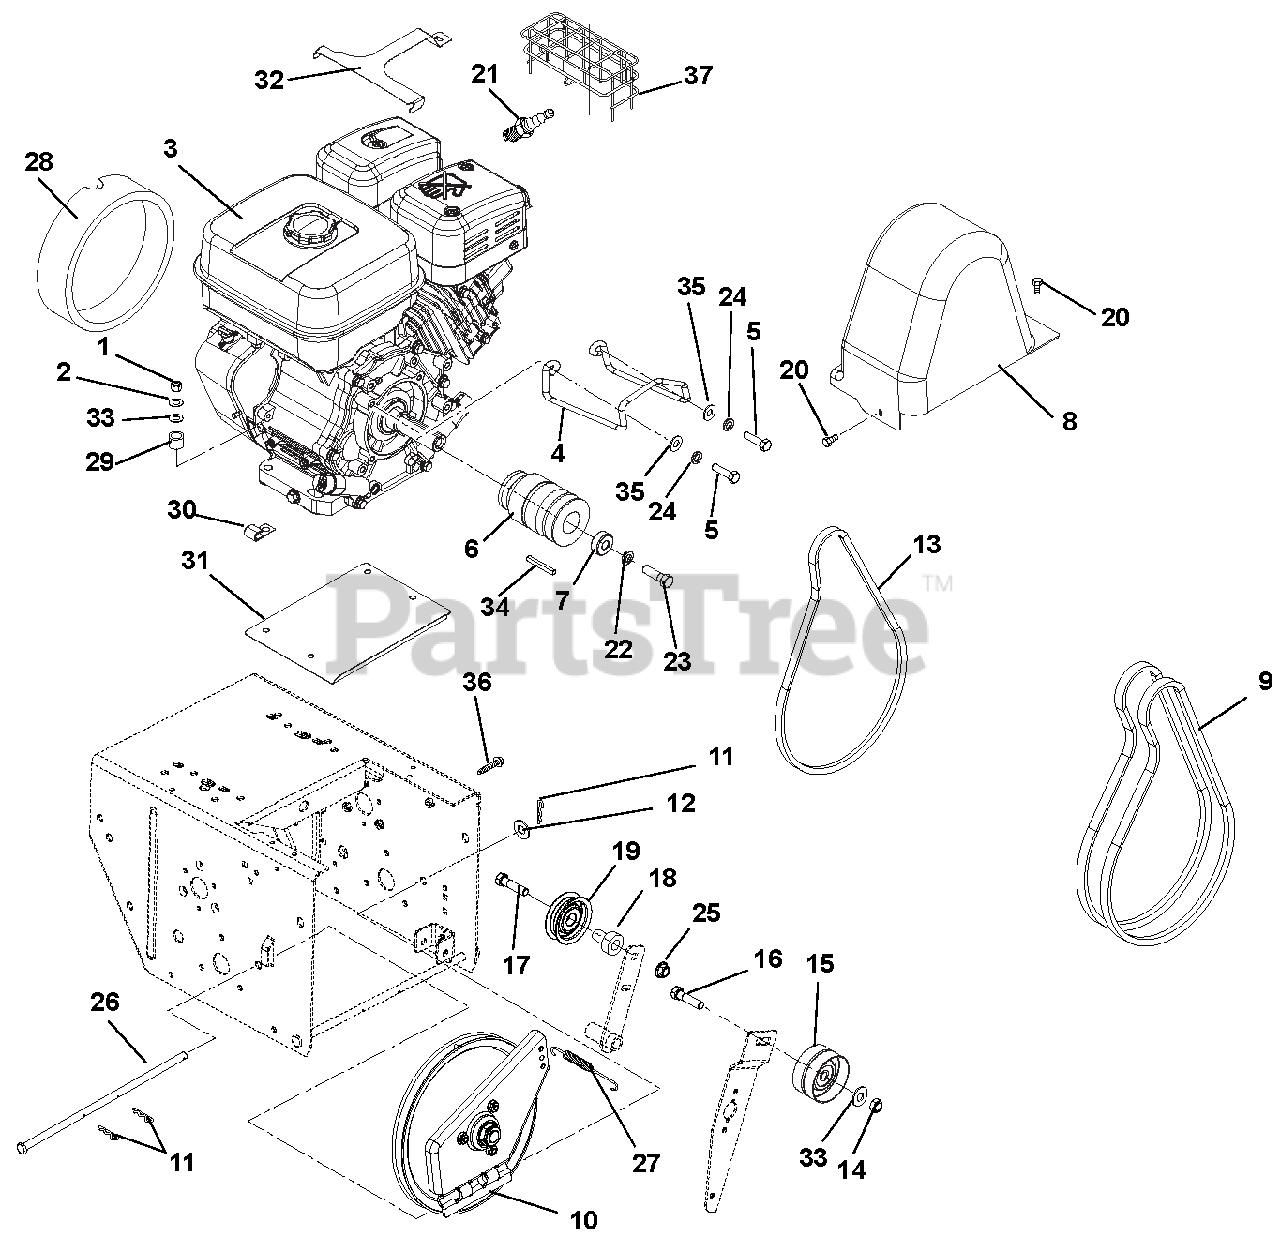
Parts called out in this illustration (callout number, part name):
1	@NUT-HEX .31-18 YWZC
2	WSHR-LK .312X.097 HVY YWZC
3	ENGINE,SUBARU EX27 AS 120V
4	FINGER, BELT
5	BLT-HEX .31-24X.75 YWZC GR5
6	SHEAVE, SUBARU EX27
7	BSHG-SPACER .47X1.25X.50
8	COVER, BELT-TALL PRO
9	V-BELT, HA-RAW EDGE (SET)
10	PLATE, SWING ASSEMBLY-DEEP
11	PIN-HAIR, ENDRIES #25 YWZC
12	@WSHR-FL-STL.406X.812X.065 YWZ
13	V-BELT, 3L-RAW EDGE
14	@NUT-LK-CTR-JAM .375-16 YWZC
15	IDLER, FLAT-2.75 OD X .375 ID
16	@BLT-RHDSSQNK .38-16X1.75 G5YZ
17	@BLT-HEX .31-18X1.25 GR5 YWZC
18	SPCR, BRG .315X.50X.688X.281
19	IDLER
20	SCR-TAP .25-20X.50 LGHWH TR YZ
21	PLUG, SPARK - TEC. SNO-THRO
22	@WSHR-LK .44X.109 REG YWZC
23	BLT-HEX .44-20X1.50 G5 YZ EP80
24	WSHR-LK .312X.097 HVY YWZC
25	@NUT-LK-TOP-FLG .31-18 YWZC
26	PIN, PIVOT
27	SG-TENS .048X.50X2.8
28	FOAM COVER, RECOIL-SUBARU
29	BSHG-SLV .325X.400X.795
30	J-CLAMP
31	BAFFLE, WATER-PRO SERIES
32	GUARD, SNOW-SUBARU
33	@WSHR-FL-STL.38X.875X.083 YWZC
34	KEY .25X.25X2.25
35	@WSHR-FL-STL.344X.688X.065YWZC
36	@SCR-TAP .25-20X1.50 HWH TR YZ
37	MUFFLER GUARD, SUB EX270JO930
